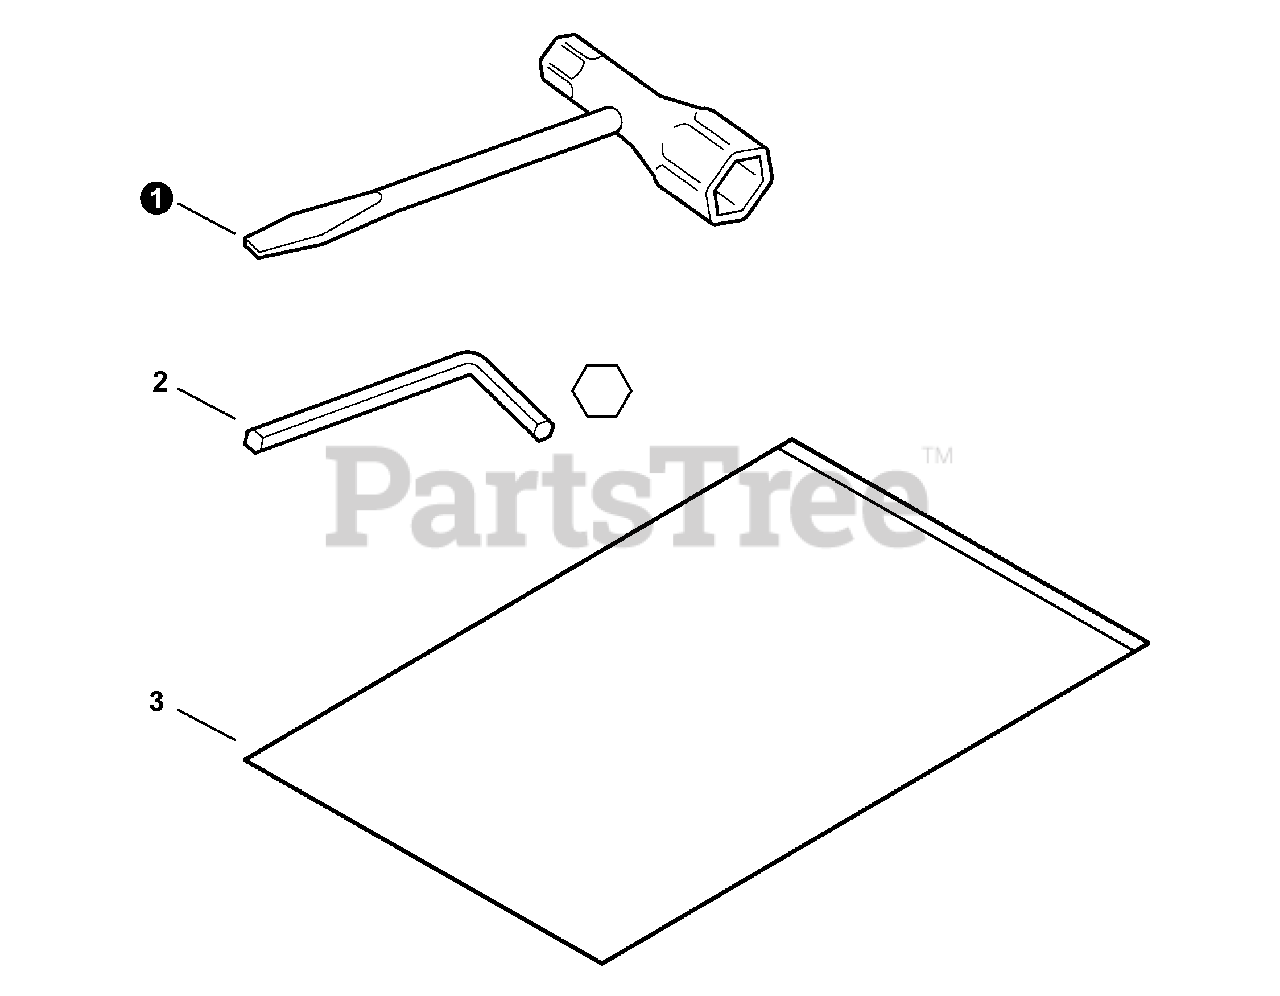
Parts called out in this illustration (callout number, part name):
1	T-WRENCH 16×13
2	WRENCH, ALLEN 4MM
3	BAG, TOOL
